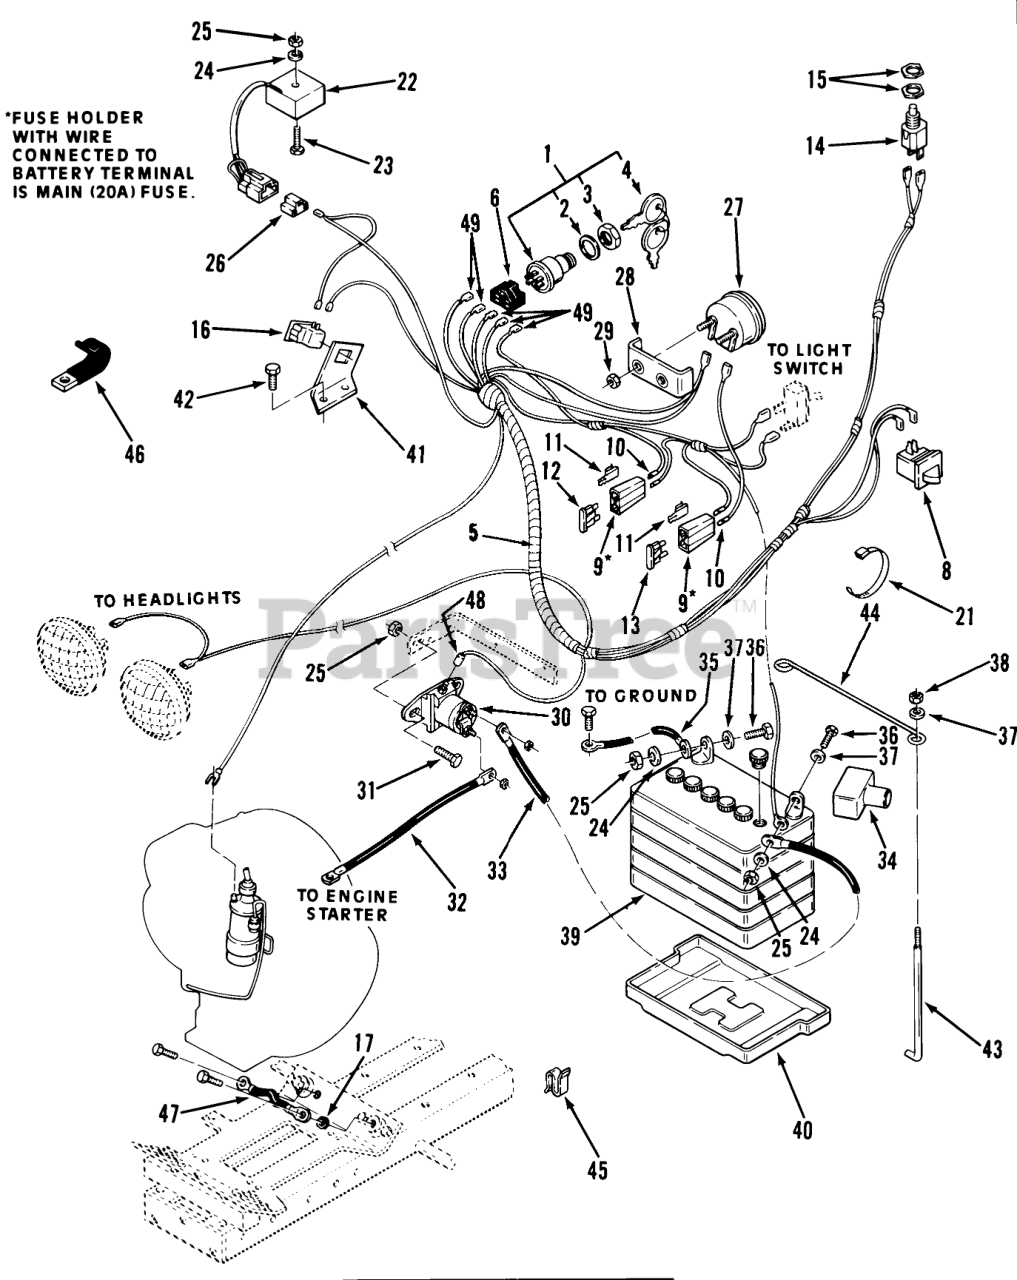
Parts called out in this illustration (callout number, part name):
1	SWITCH-IGNITION
2	LOCKWASHER
4	Key-EL
5	Wiring Harness
6	CONNECTOR-5 WAY-SERV
8	SWITCH INTERLOCK
9	AUTO-FUSEBLOCK TERM
10	TERMINAL-FUSE
12	FUSE-BLADE, 15 AMP
13	FUSE-BLADE, 25 AMP
14	SWITCH
15	NUT-HEX
16	SWITCH INTERLOCK
17	LOCKWASHER
21	PLASTIC TIE
22	RECTIFIER
23	Bolt 1/4-20 X 1 1/2
24	Washer
25	Nut
26	TERMINAL-TAB RCPT
27	AMMETER W/CLAMP
28	Clamp
29	HEX NUT 10-32 E.S.
30	Solenoid
31	Screw
32	WIRE-GROUND
33	Cable
34	Boot
35	Wire
36	Bolt
38	Nut
39	Battery
40	TRAY BATTERY
41	BRACKET-SWITCH (NS)
42	Bolt
44	ROD-HOLD DOWN
45	SPEED CLIP
46	CLIP
47	WIRE-GROUND
48	Terminal Part of 5
49	Terminal
